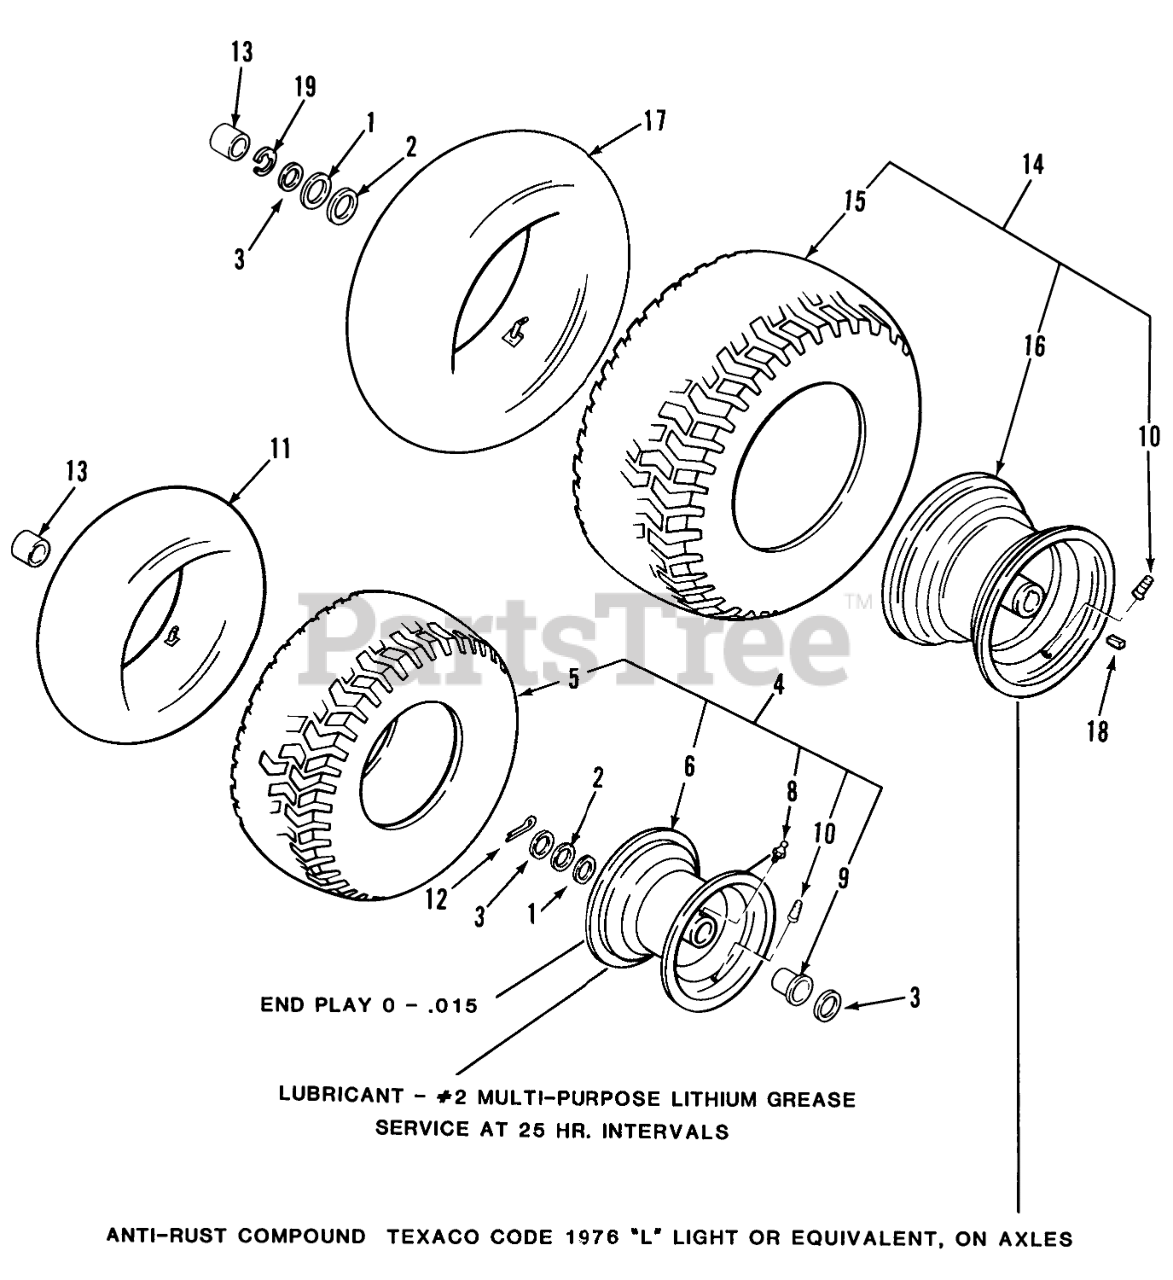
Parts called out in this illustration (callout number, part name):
1	WASHER-SHIM
2	WASHER
3	WASHER-FLAT
4	Front Wheel and Tire 15 x 5.00-6 (includes items 6, 8, 9 & 10) 208-4, 211-4, 211-5
4	Front Wheel and Tire 15 x 6.00-6 (includes items 6, 8, 9 & 10) 212-6
5	TIRE15 X 6.00-6
6	Front Wheel Assy (includes Wheel w/items 8, 9 & 10) 208-4, 211-4, 211-5
6	Front Wheel Assy (includes Wheel w/items 8, 9 & 10) 212-6
8	ZERK-GREASE
9	BUSHING
10	VALVE
12	COTTER PIN-4
13	HUB CAP
13	HUB CAP-FLAT BLACK
14	Rear Wheel and Tire 18 x 8.50-8 211-4
14	Rear Wheel & Tire-212-5
15	TIRE 18 X 8.50 X 8
15	TIRE 18 X 9.50-8
16	Rear Wheel 211-4
16	ASSY WHEEL
17	Tube-Inner
18	SQ KEY
19	E Ring
